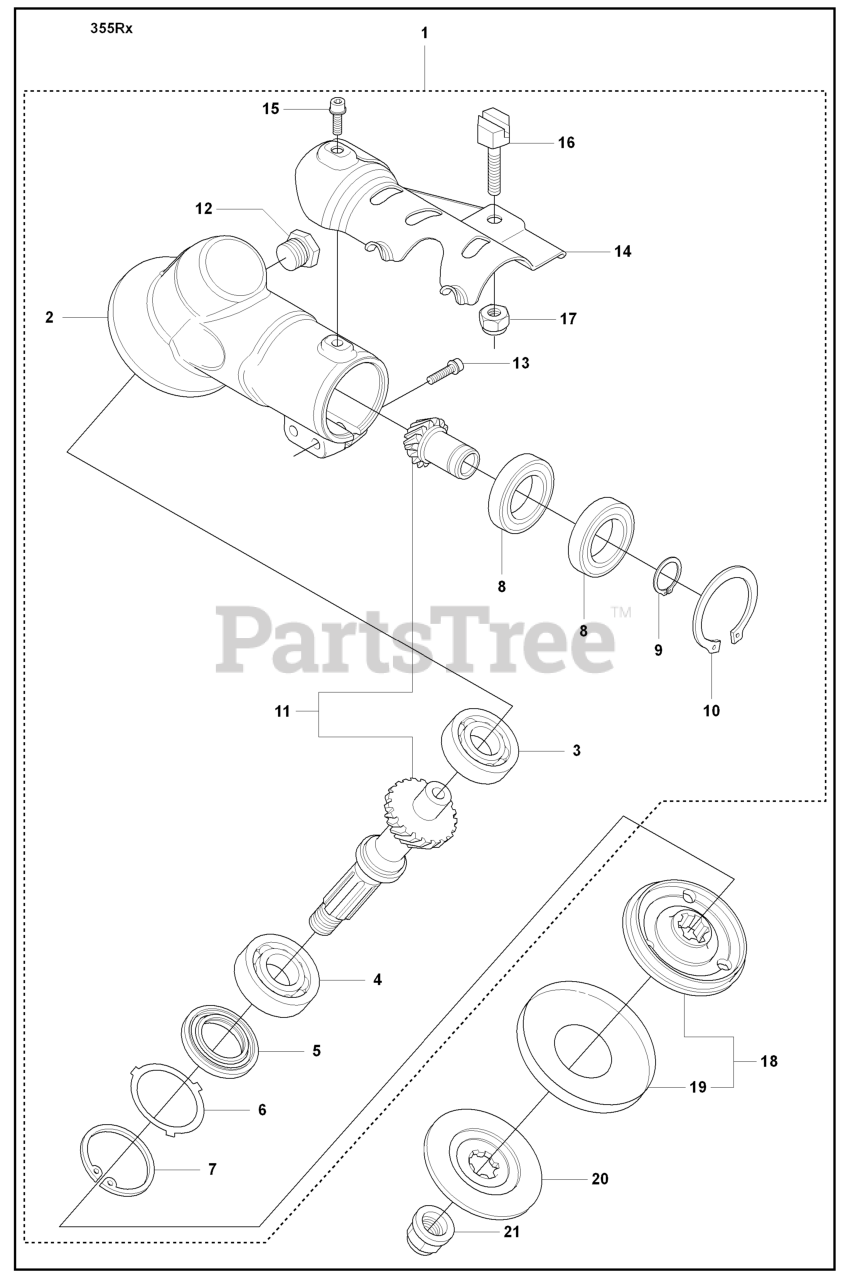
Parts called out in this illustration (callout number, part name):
2	GEAR HOUSING
3	BALL BEARING
4	BALL BEARING
7	RETAINING RING SGH 35
8	BALL BEARING
9	RETAINING RING SGA 15
10	RETAINING RING
11	BEVEL GEAR
14	ATTACHMENT PLATE
17	LOCKNUT M6
19	GRASS SEALING
20	SUPPORT FLANGE
21	BLADE NUT
